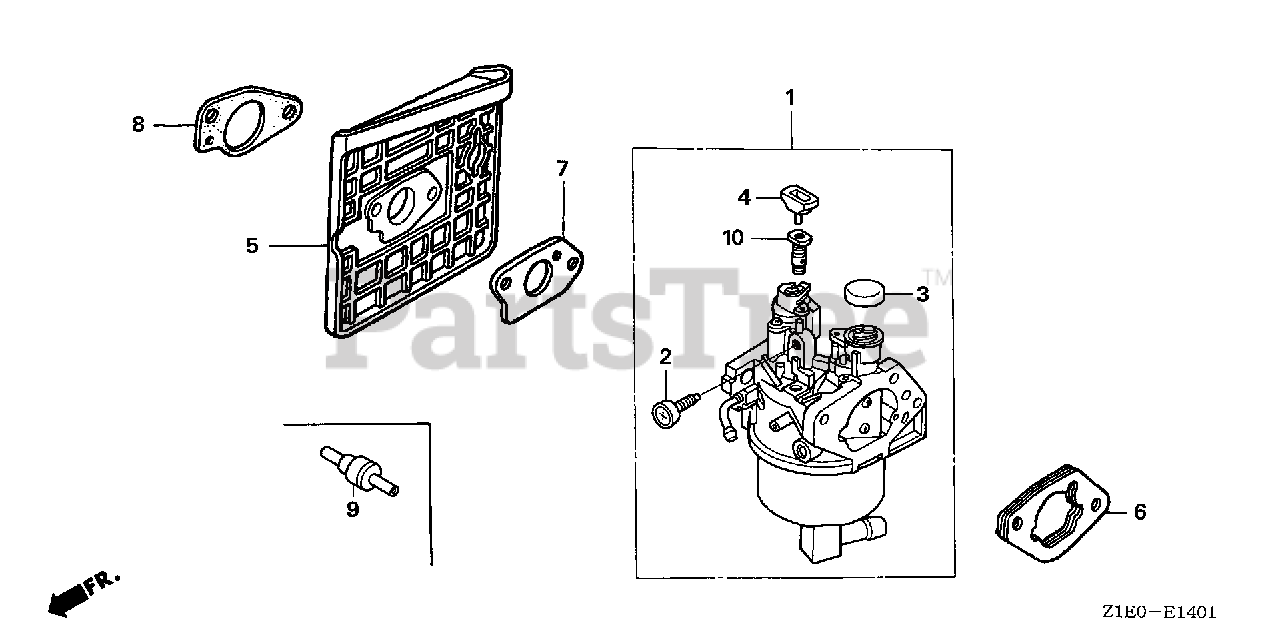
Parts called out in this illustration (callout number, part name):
1	CARBURETOR ASSY. (BEL7A C)
2	SCREW, THROTTLE STOP
3	CAP, CHOKE LEVER DUST
4	COLLAR, SET
5	INSULATOR, CARBURETOR
6	SPACER, CARBURETOR
7	GASKET, CARBURETOR
8	GASKET, INSULATOR
9	VALVE, DASHPOT CHECK
10	JET SET, PILOT (#45)
